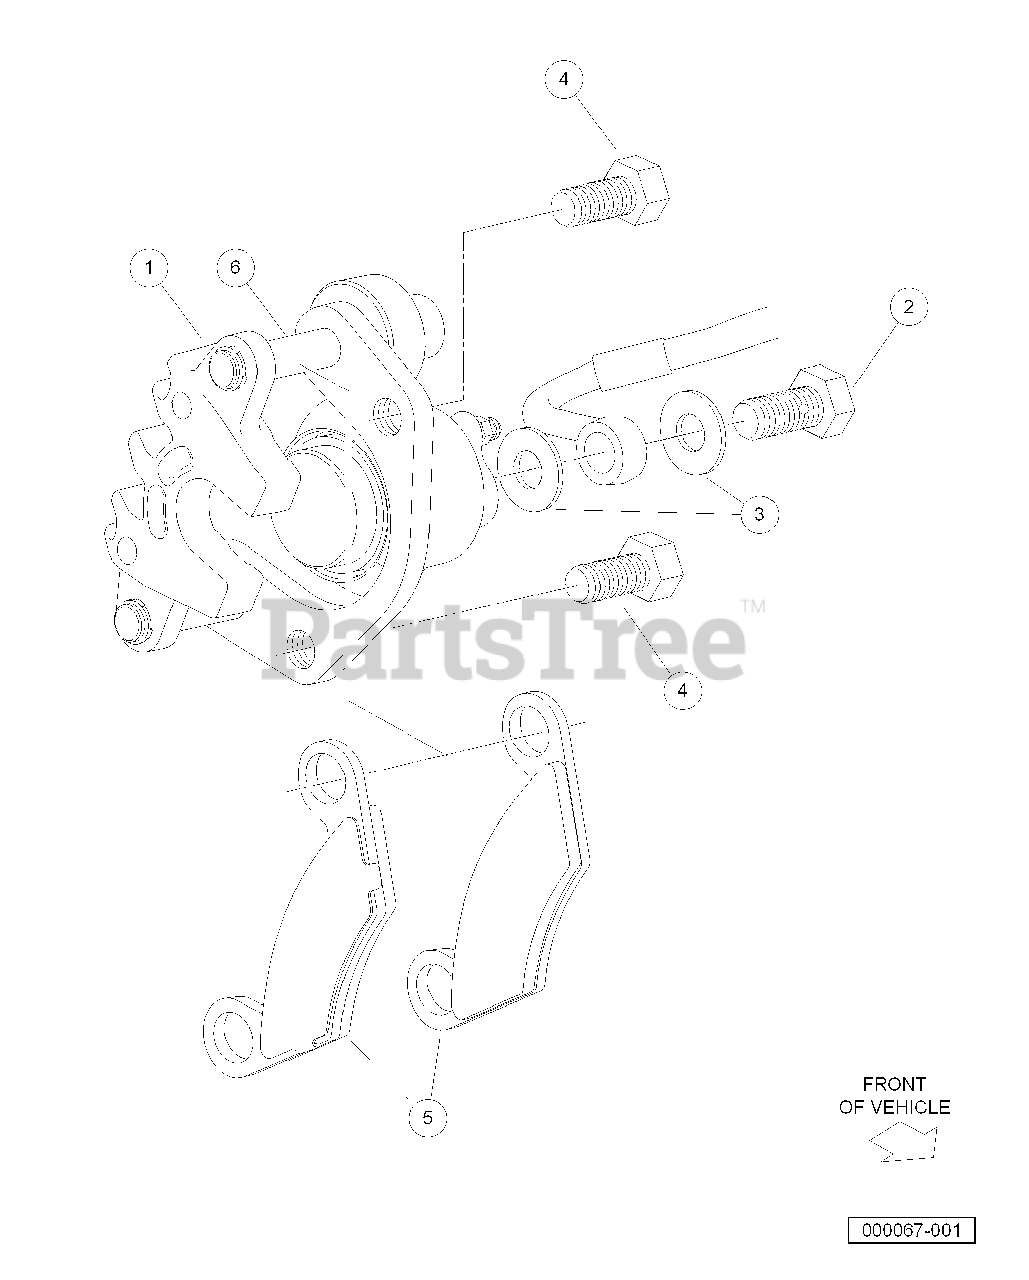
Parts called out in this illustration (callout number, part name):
1	Brake Caliper, Front, with Brake Pads
2	Bolt, Banjo, M10x1x19
3	Washer, Copper, M10 Crush
4	Bolt Flange Head, 3/8-24x.750 with Loctite
5	Service Kit, Brake Pad
6	Pin, Slide, 7/16
